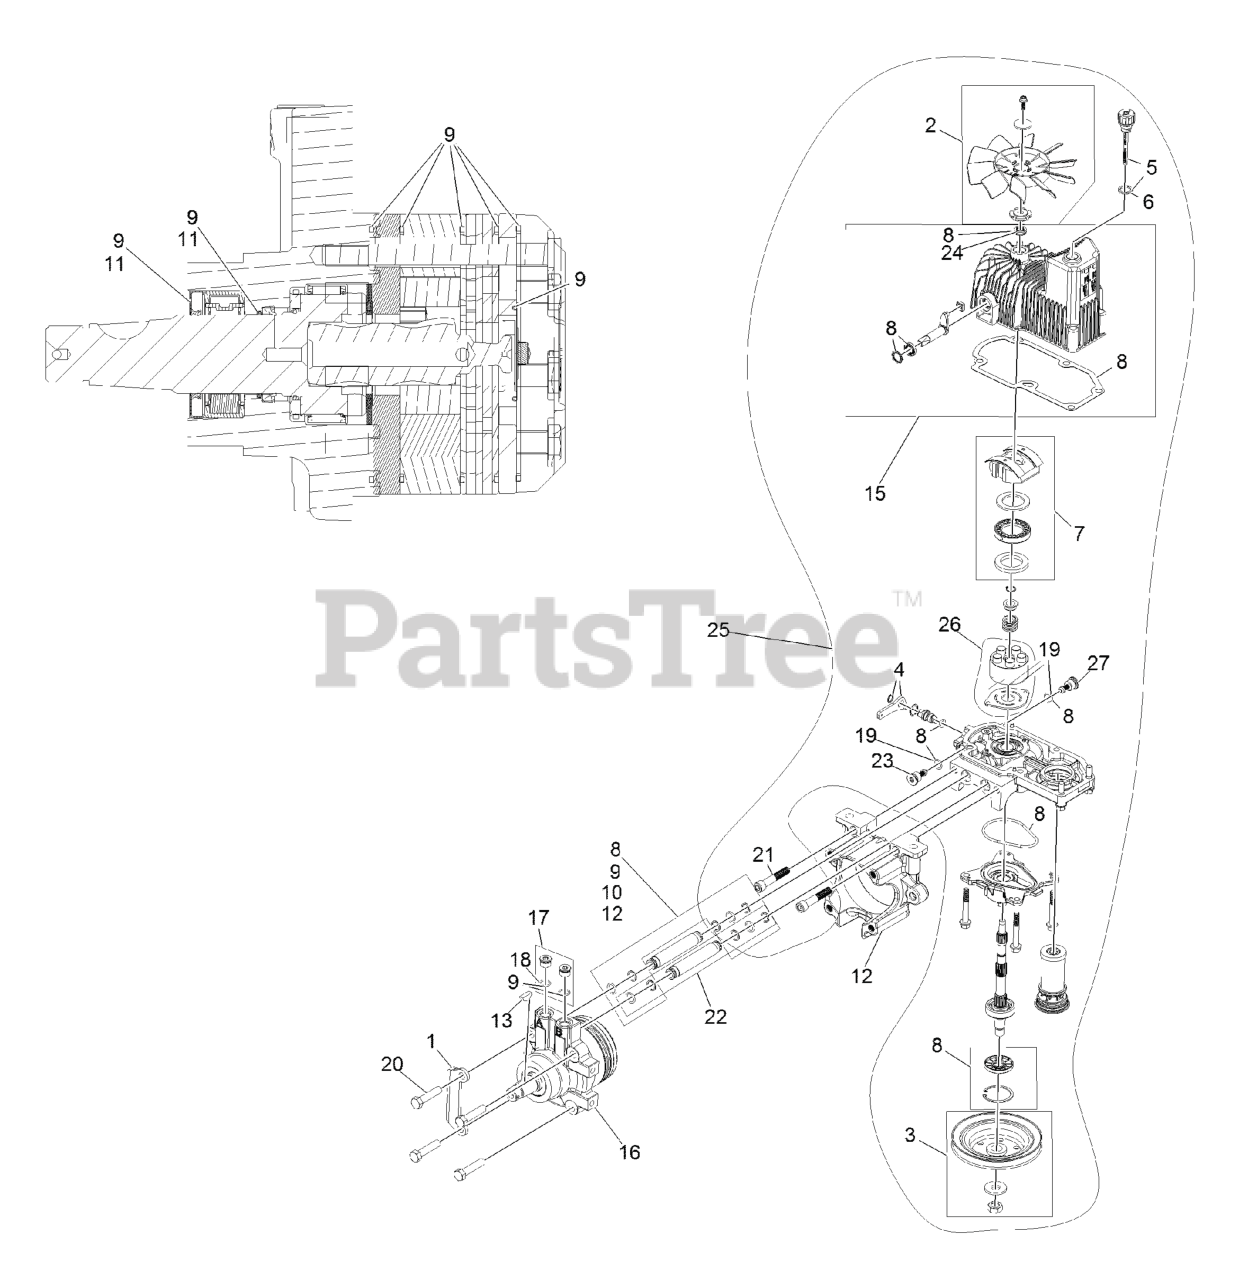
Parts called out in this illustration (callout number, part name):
1	Plate, Horse Shoe Mount
2	Kit, 7.8 In Fan
3	PULLEY KIT
4	HANDLE-BYPASS VALVE, HYDRO
5	DIPSTICK-HYDRO W/GASKET
6	GASKET-DIPSTICK, HYDRO
7	SWASH BLOCK KIT
8	Kit, Pump Seal
9	MOTOR SEAL KIT
10	TUBE SEAL KIT
11	OUTPUT SHAFT SEAL KIT
12	NOSE CUP-UHT
13	KEY-WOODRUFF
15	Kit, Housing-Hydro RH
16	MOTOR-HYDRAULIC RH 240CC
17	MAGNETIC PLUGS SERVICE KIT
19	O-RING-CHECK VALVE
20	SCREW HH
21	SCREW-HSH
22	HYDRAULIC TUBE KIT
23	SHOCK VALVE, 12CC HYDRO
24	SEAL-FAN DRIVE
25	Kit, Pump Section 12Cc RH
26	Kit - 12Cc Port Plate,Rotate Grp
27	Shock Valve Orificed 3800
